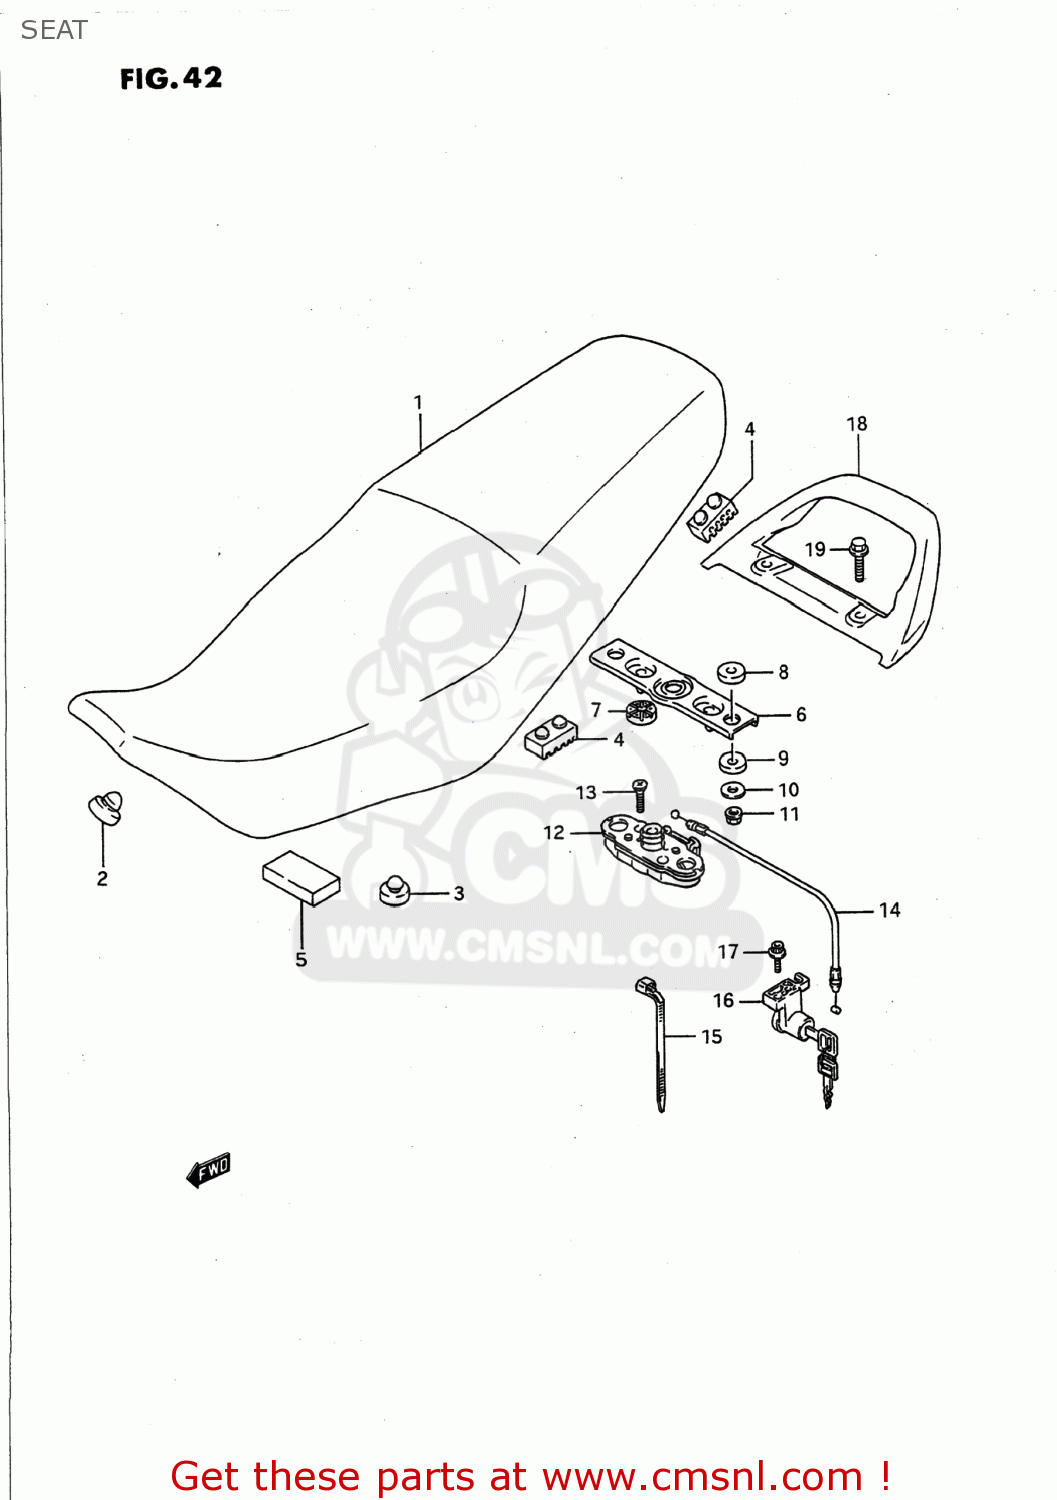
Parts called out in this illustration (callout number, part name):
1	SEAT SET
2	CUSHION
3	CUSHION
4	CUSHION,SEAT(40X20X15)
5	CUSHION(30X60X10)
6	STRIKER,SEAT LOCK
7	CUSHION,SEAT LOCK(10X22X6)
8	CUSHION,UPR
9	CUSHION,LWR
10	WASHER
11	NUT
12	LOCK ASSY,SEAT STRIKER
13	SCREW
14	CABLE,SEAT LOCK
15	CLAMP(L:125)
16	LOCK SET
17	BOLT
18	HANDLE,PILLION RIDER
19	BOLT
